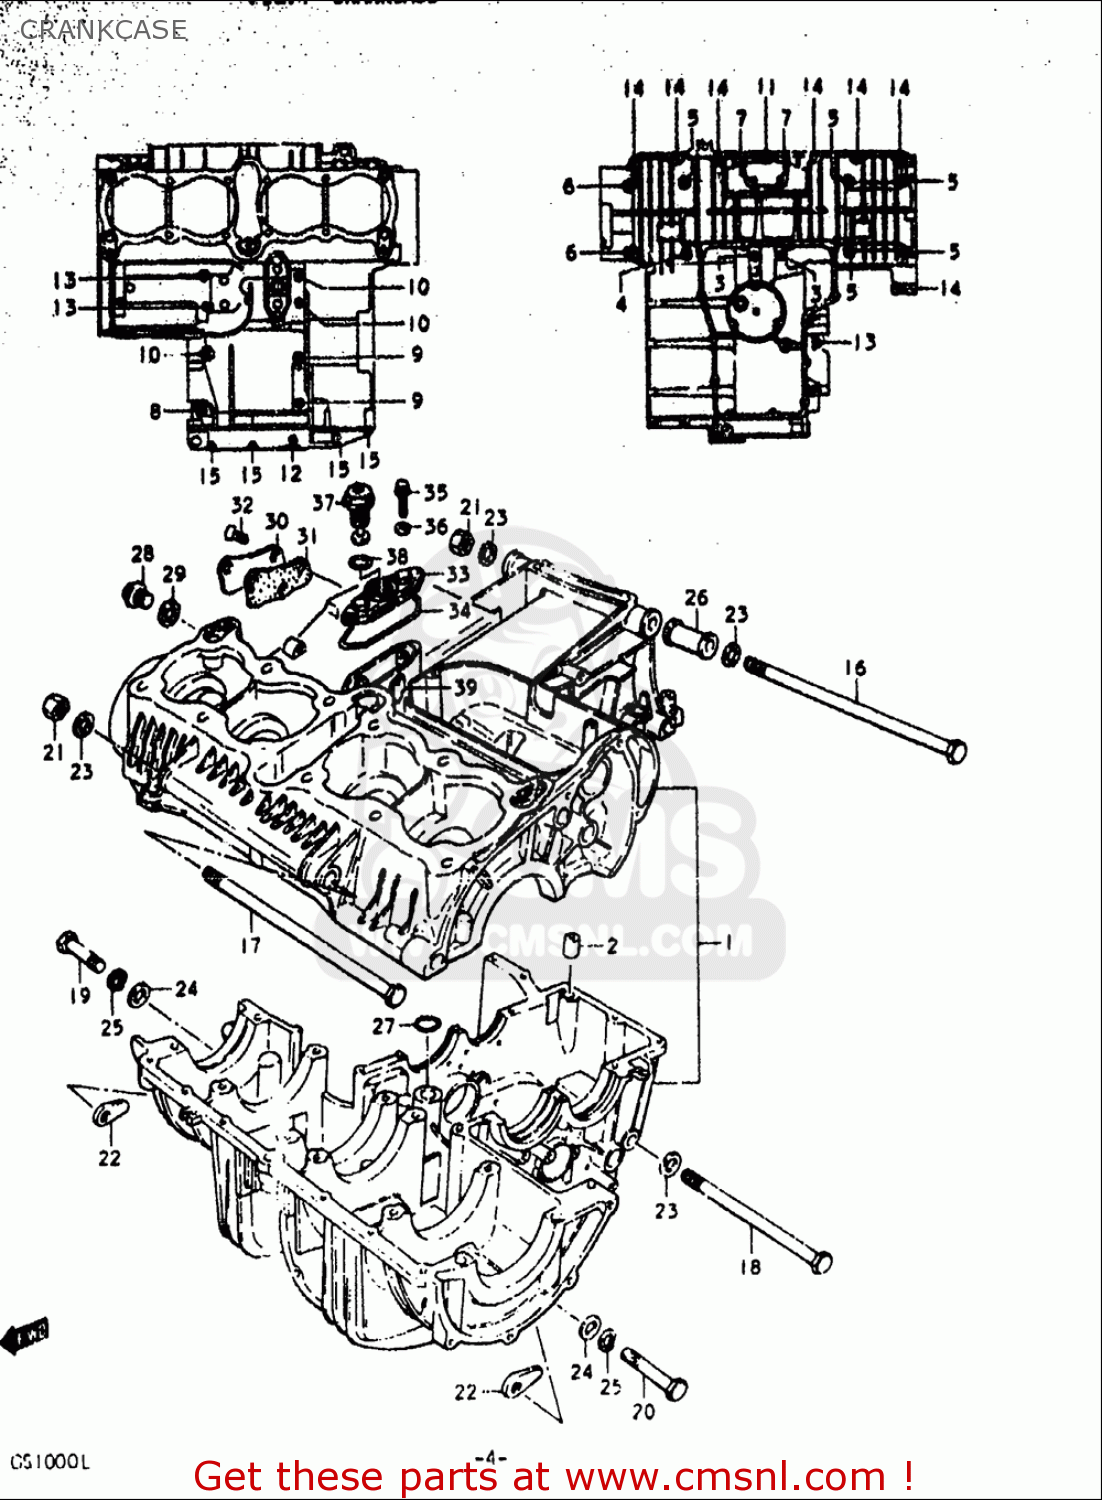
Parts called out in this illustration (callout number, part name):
2	PIN
3	BOLT(8X125)
4	BOLT(8X100)
5	BOLT
6	BOLT
7	BOLT
8	BOLT
9	BOLT
10	BOLT
11	BOLT
12	BOLT
13	BOLT
14	BOLT
15	BOLT
16	BOLT 10X265
17	BOLT 10X250
18	BOLT(10X165)
19	BOLT
20	BOLT
21	NUT
22	NUT
23	WASHER
24	WASHER(10.5X20X3.2)
25	WASHER,LOCK
26	SPACER
27	O RING(D:3.2,ID:12.9)
28	PLUG(14X12)
29	GASKET(14X19.2X2) (NAS)
30	CAP,OIL GALLERY
31	GASKET,OIL GALLERY CAP (NAS)
32	SCREW
33	HOUSING,OIL PRESSURE SWITCH
34	O RING,PRESSURE SWITCH HOUSING
35	BOLT
36	GASKET(5.8X13X1.2) (NAS)
37	SWITCH ASSY,OIL PRESSURE
38	O RING(D:1.9,ID:18.8)
